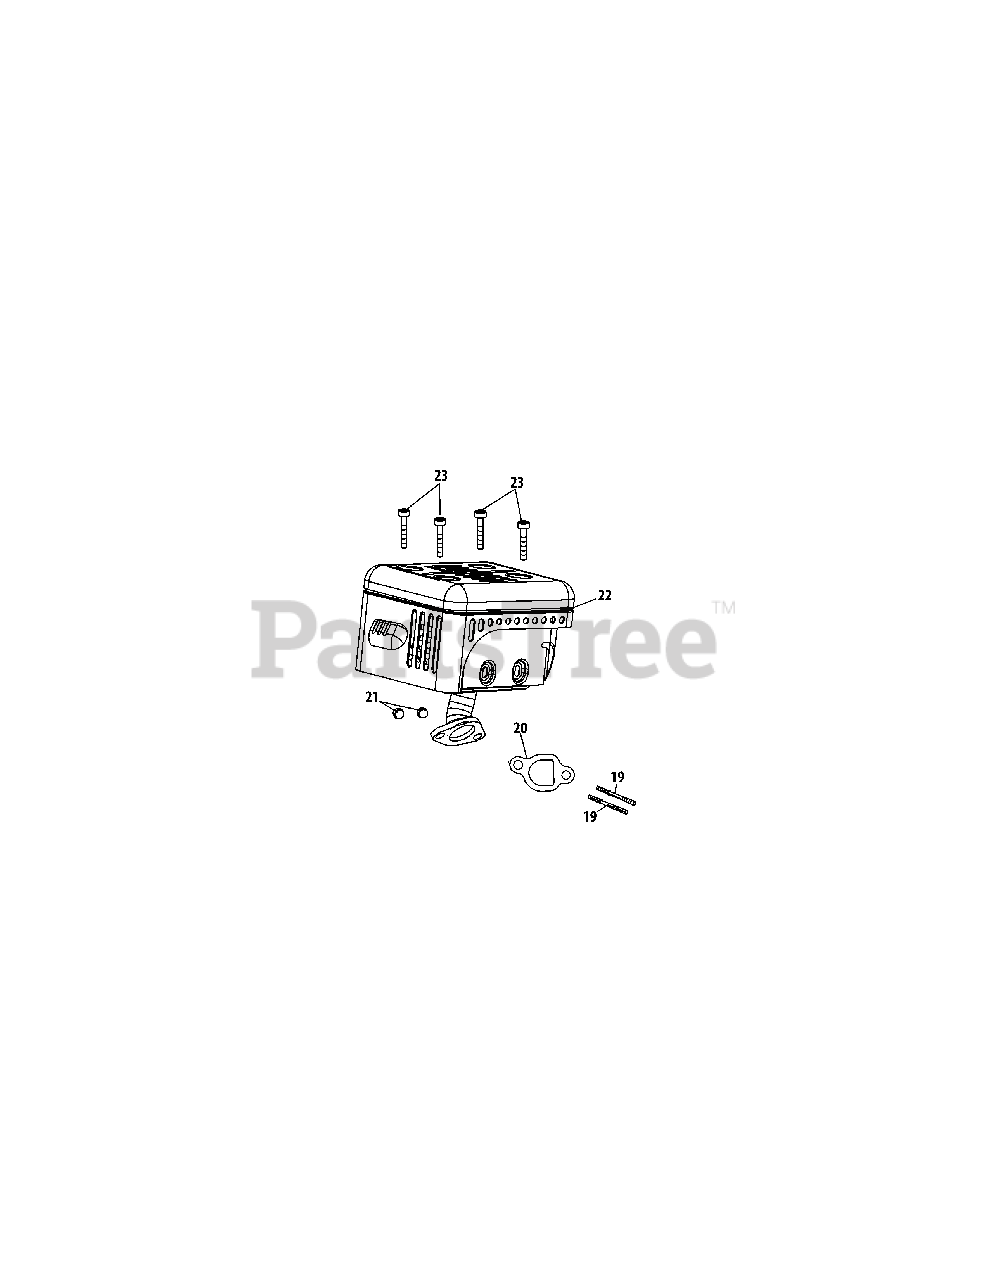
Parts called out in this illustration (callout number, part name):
19	Muffler Stud M8×36
19	Muffler Stud Assembly
20	Muffler Gasket
22	Muffler Assembly
23	Bolt
